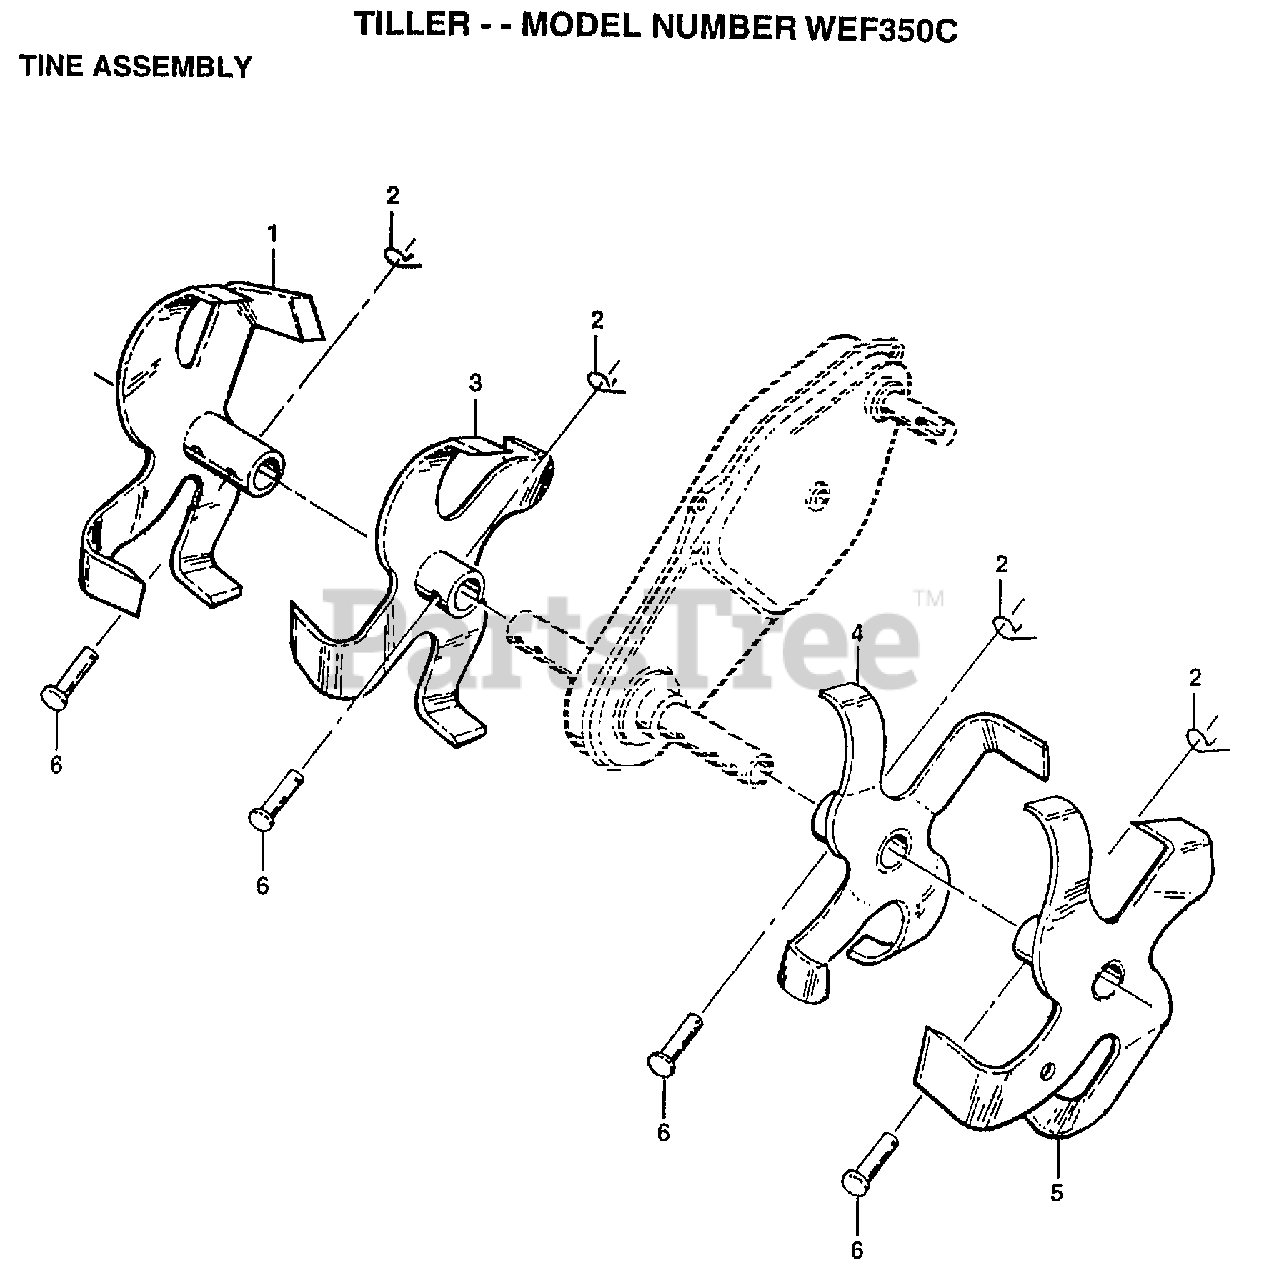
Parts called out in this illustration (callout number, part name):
1	TINE ASSY RH
2	SPRING.RETAINER
3	TINE ASSY RH
4	TINE INN LH TI
5	TINE ASS'Y LH
6	DRILLED RIVET RT
